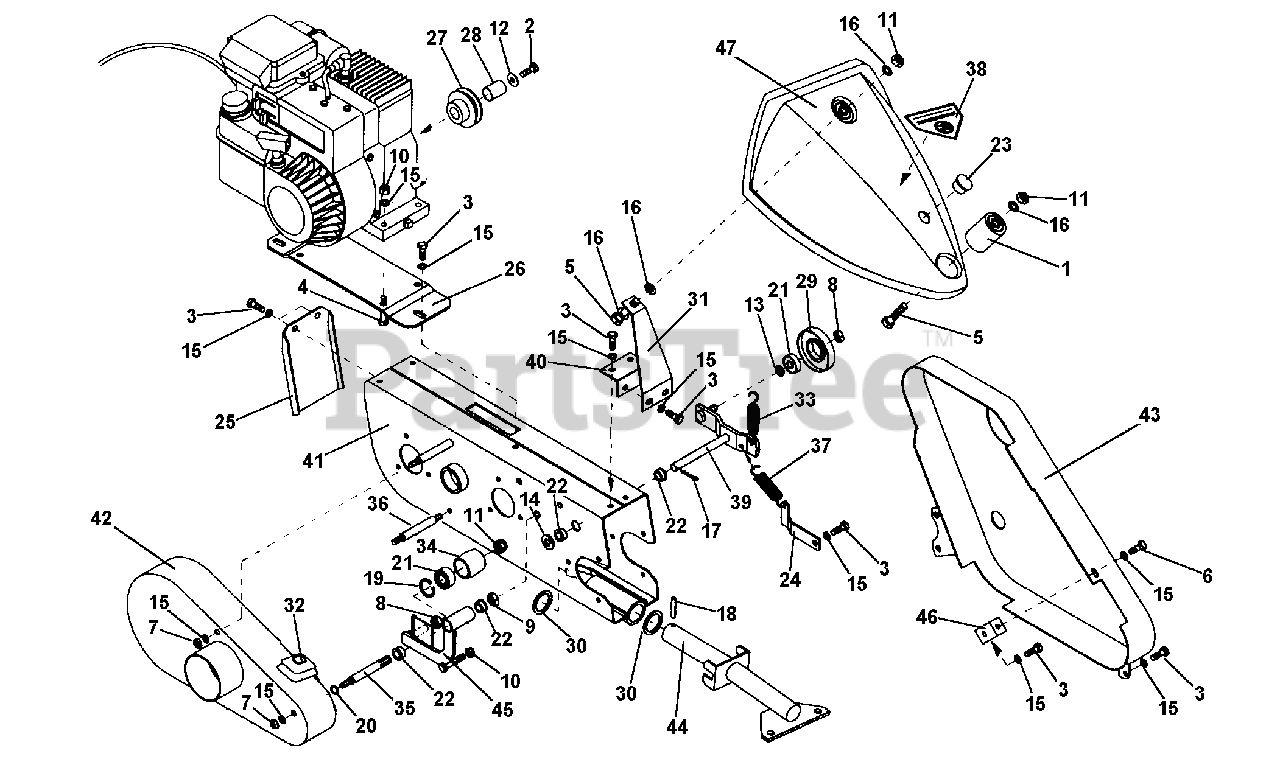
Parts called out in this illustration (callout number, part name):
1	SILENT BLOCK
2	SCREW 5/16 X 7/8"
3	SCREW M8X20
4	SCREW M8X40
5	SCREW M10X45
6	SCREW M10X35
10	NUT, SELF LOCKING M8
11	NUT, SELF LOCKING M10
12	WASHER, FLAT
13	WASHER, FLAT M10.5
14	WASHER, FLAT M13
15	WASHER, M8.3
16	WASHER, LOCK M10.5
18	LOCKING PIN M6X40
19	CIRCLIP, INTERNAL
20	CIRCLIP, EXTERNAL
21	BEARING M10X30X9
24	SPRING SUPPORT
26	ENGINE BRACKET
27	ENGINE PULLEY
29	IDLER PULLEY
31	HOOD BRACKET
35	IDLER SHAFT
36	SPACER SHAFT
44	CUTTERBAR SUPPORT
46	BRACKET, BELT GUARD
